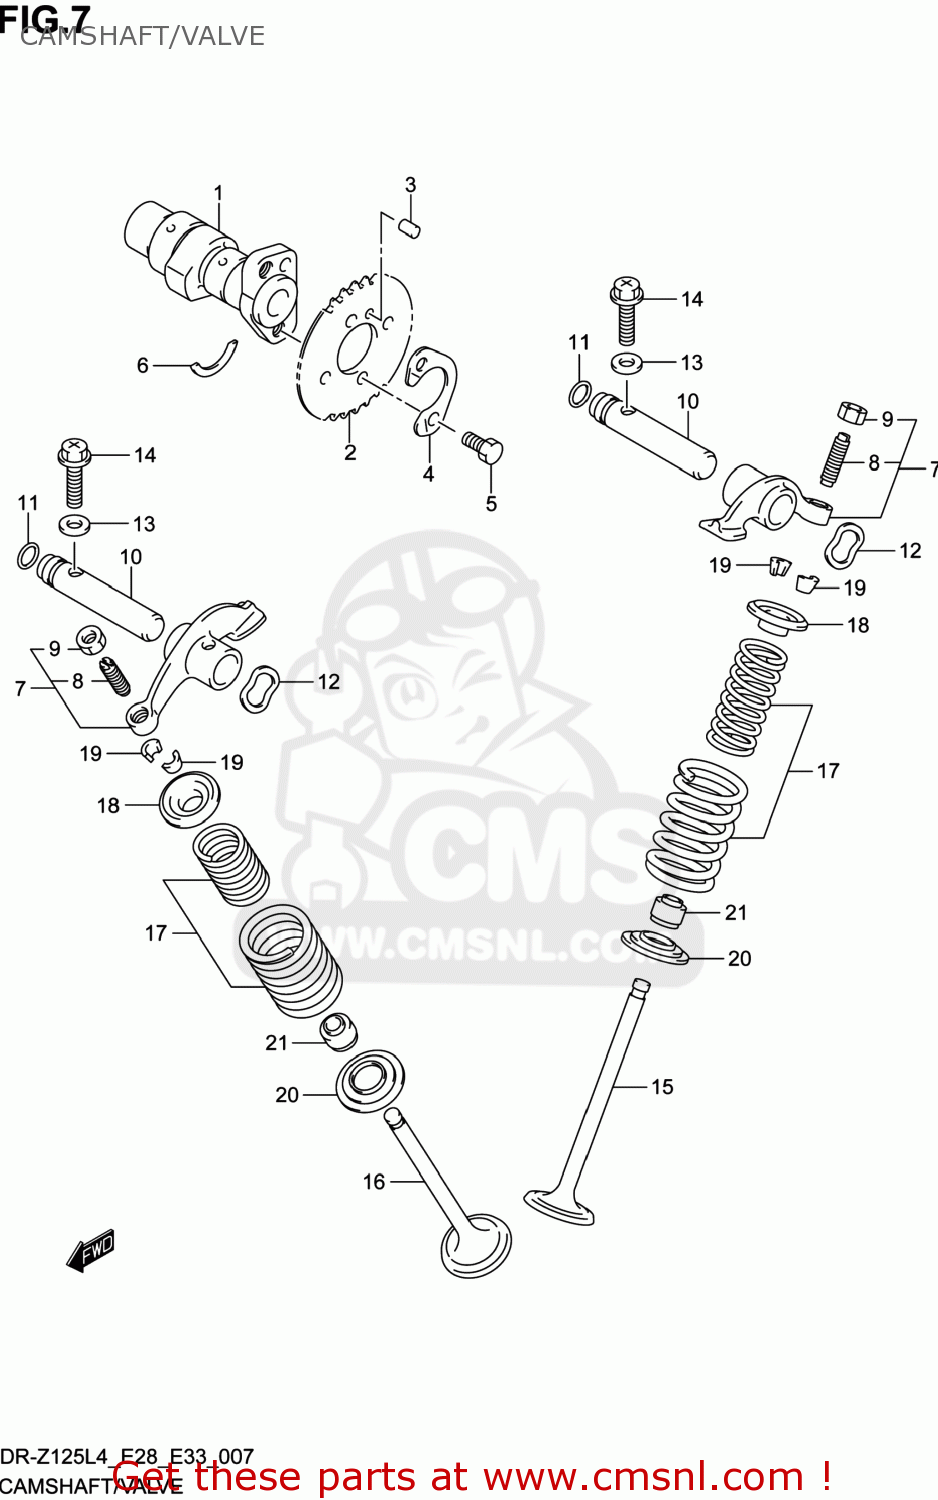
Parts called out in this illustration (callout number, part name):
1	CAMSHAFT
2	SPROCKET,CAMSHAFT
3	PIN(5X8)
4	WASHER,SPROCKET
5	BOLT(6X10.5)
6	C RING
7	ARM ASSY,VALVE ROCKER
8	SCREW,TAPPET ADJUSTING
9	NUT,ADJUSTING SCREW
10	SHAFT,VALVE ROCKET
11	O RING(D:1.9,ID:8.6)
12	WASHER
13	GASKET(5.8X13X1.2) (NAS)
14	SCREW
15	VALVE,INTAKE
16	VALVE,EXHAUST
17	SPRING SET,VALVE
18	RETAINER,VALVE SPRING
19	COTTER,VALVE
20	SEAT,VALVE SPRING
21	SEAL,OIL(5.5X11X8.2)
